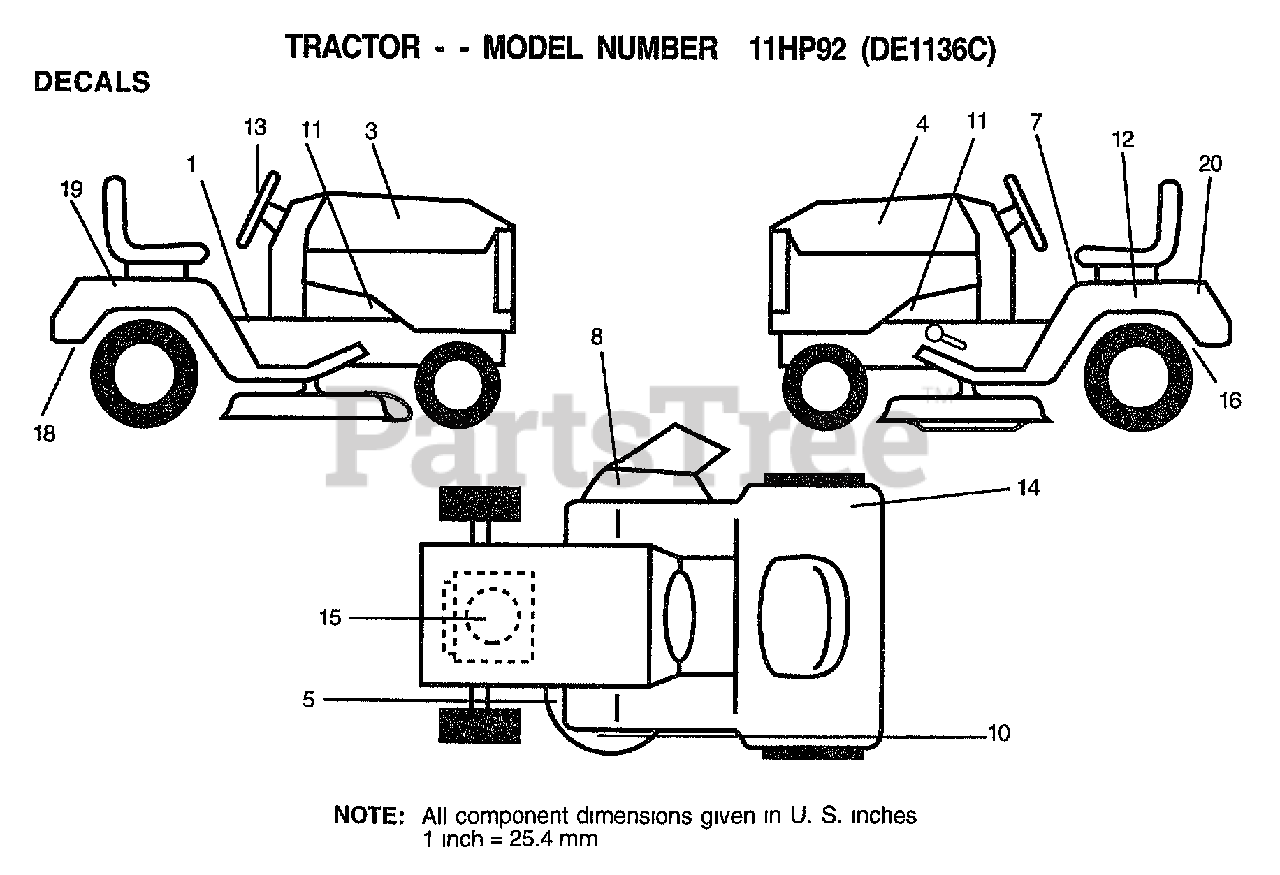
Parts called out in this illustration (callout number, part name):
1	DECAL CLUTCH/BRAK
3	DECAL.HOOD.RH
4	DECAL.HOOD.LH
5	DECAL.V.BELT
7	DECAL.READ.O.MANU
8	DECAL.DANGER.CUTF
10	DECAL.DECK.MOWER
11	"DECAL CHASSIS,HOT"
12	DECAL.BATRY.3-3908
13	DECAL.INST.STEERING
15	DECAL, ENGINE
16	DECAL.DRAWBAR.LDL
18	DECAL.EURO.ST.CE.
19	DECAL.FENDER.RH
20	DECAL FENDER LH
